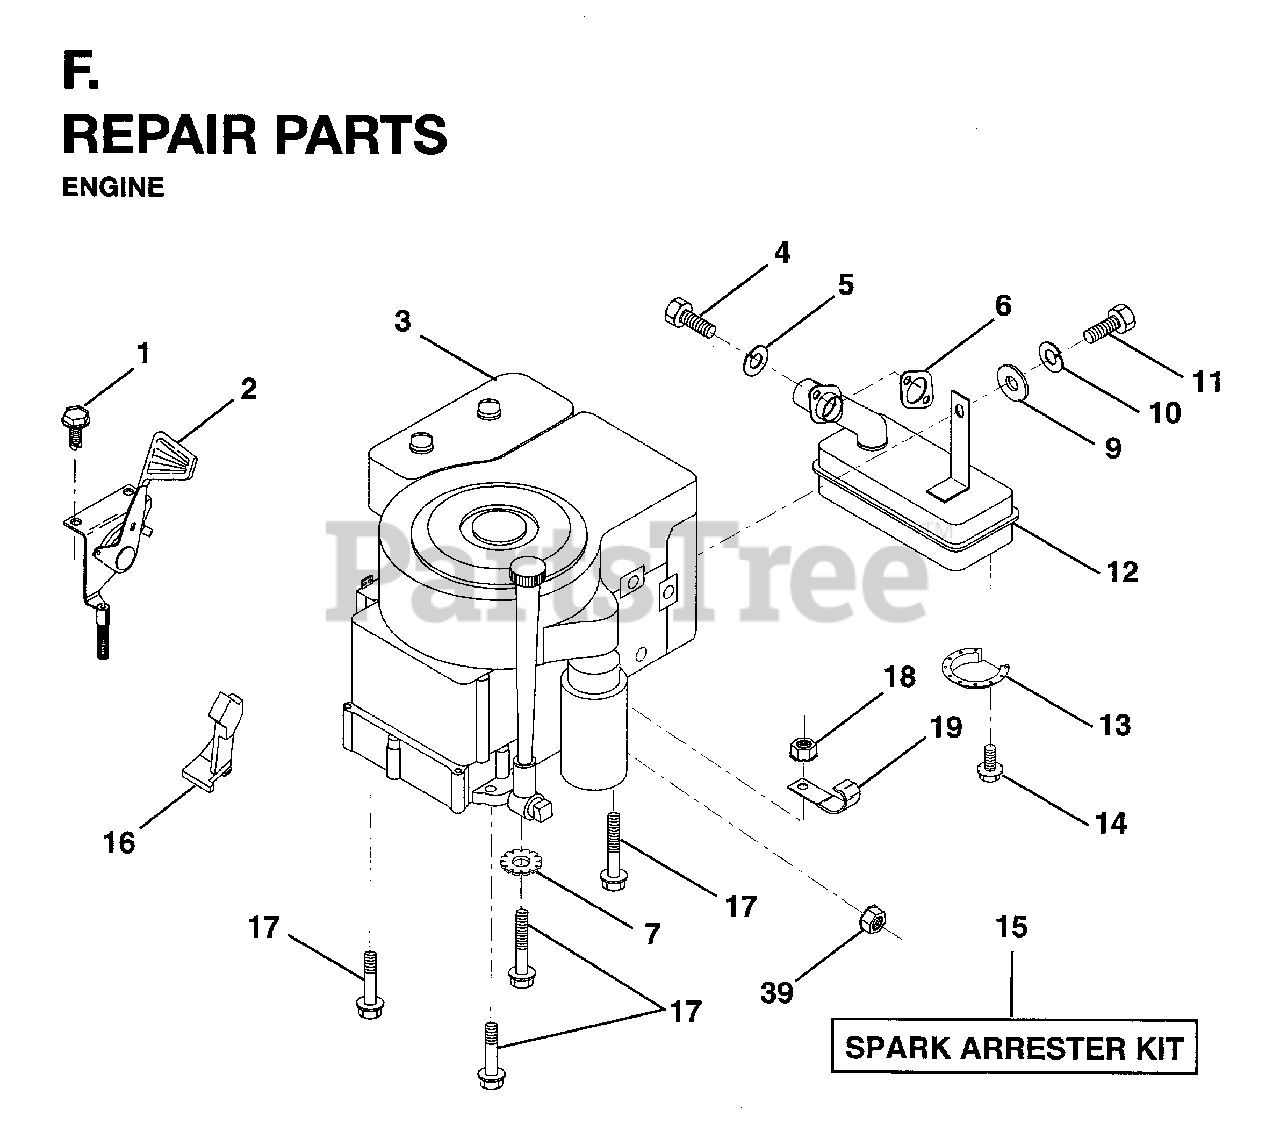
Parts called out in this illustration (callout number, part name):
2	THROTTLE CONTROL
4	SCREW
5	LOCKWASHER
7	WASHER, LOCK 3/8
9	WASHER - 26X6.5X1.6
10	LOCKWASHER
13	DEFL MUFFLER LTV
14	SCREW
15	ARRESTER SPARK (OPTIONAL)
16	STOP THROTTLE
17	BOLT
19	CLIP T
39	NUT
